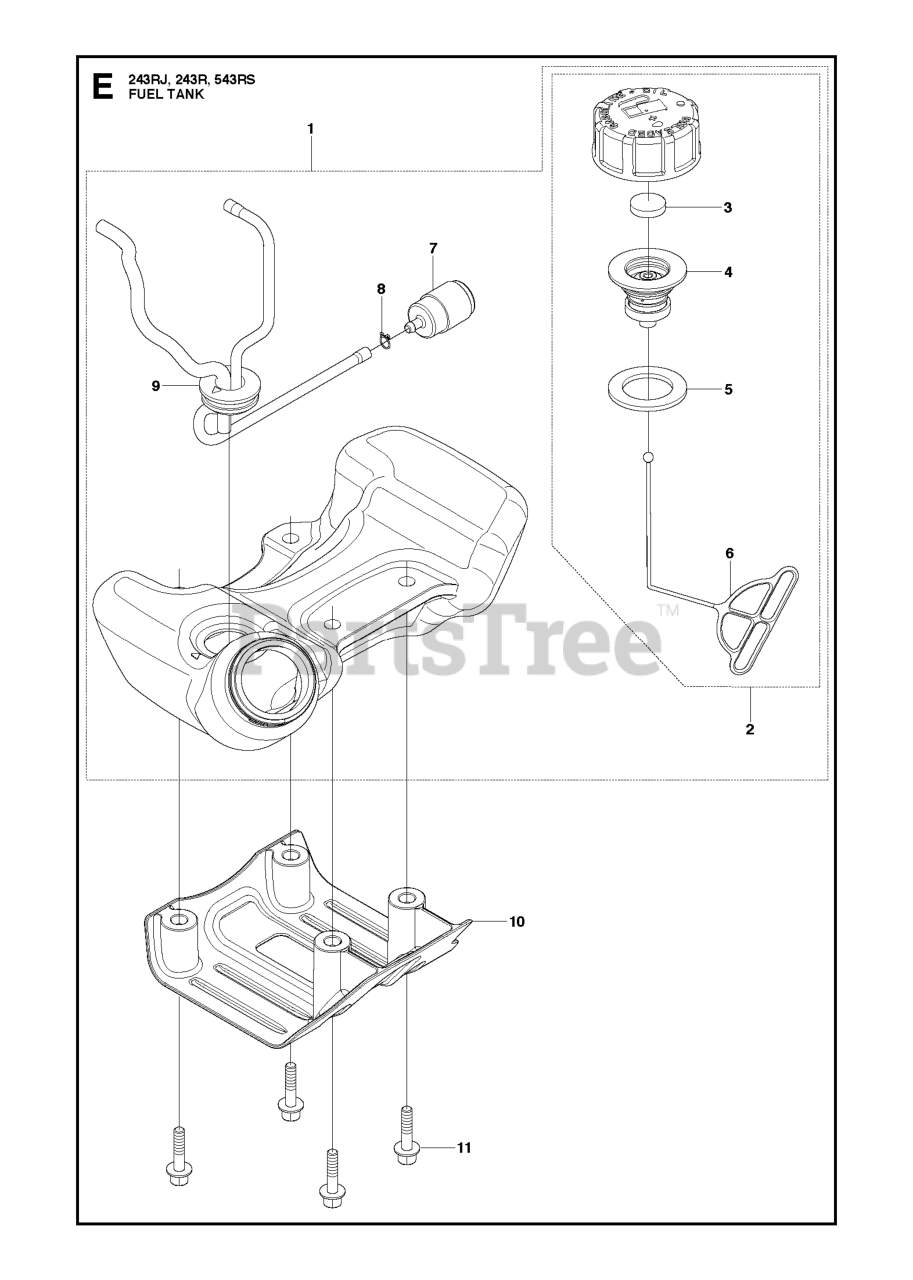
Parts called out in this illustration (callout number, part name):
1	TANK-ASSY 848GG08501
2	CAP-ASSY
3	FILTER
4	HOLDER ASSY
5	PACKING
6	STOPPER
7	FILTER
8	CLIP
9	PIPE ASSY
9	PIPE-COMP 848GG08530
10	SKID PLATE
11	BOLT M5X25
